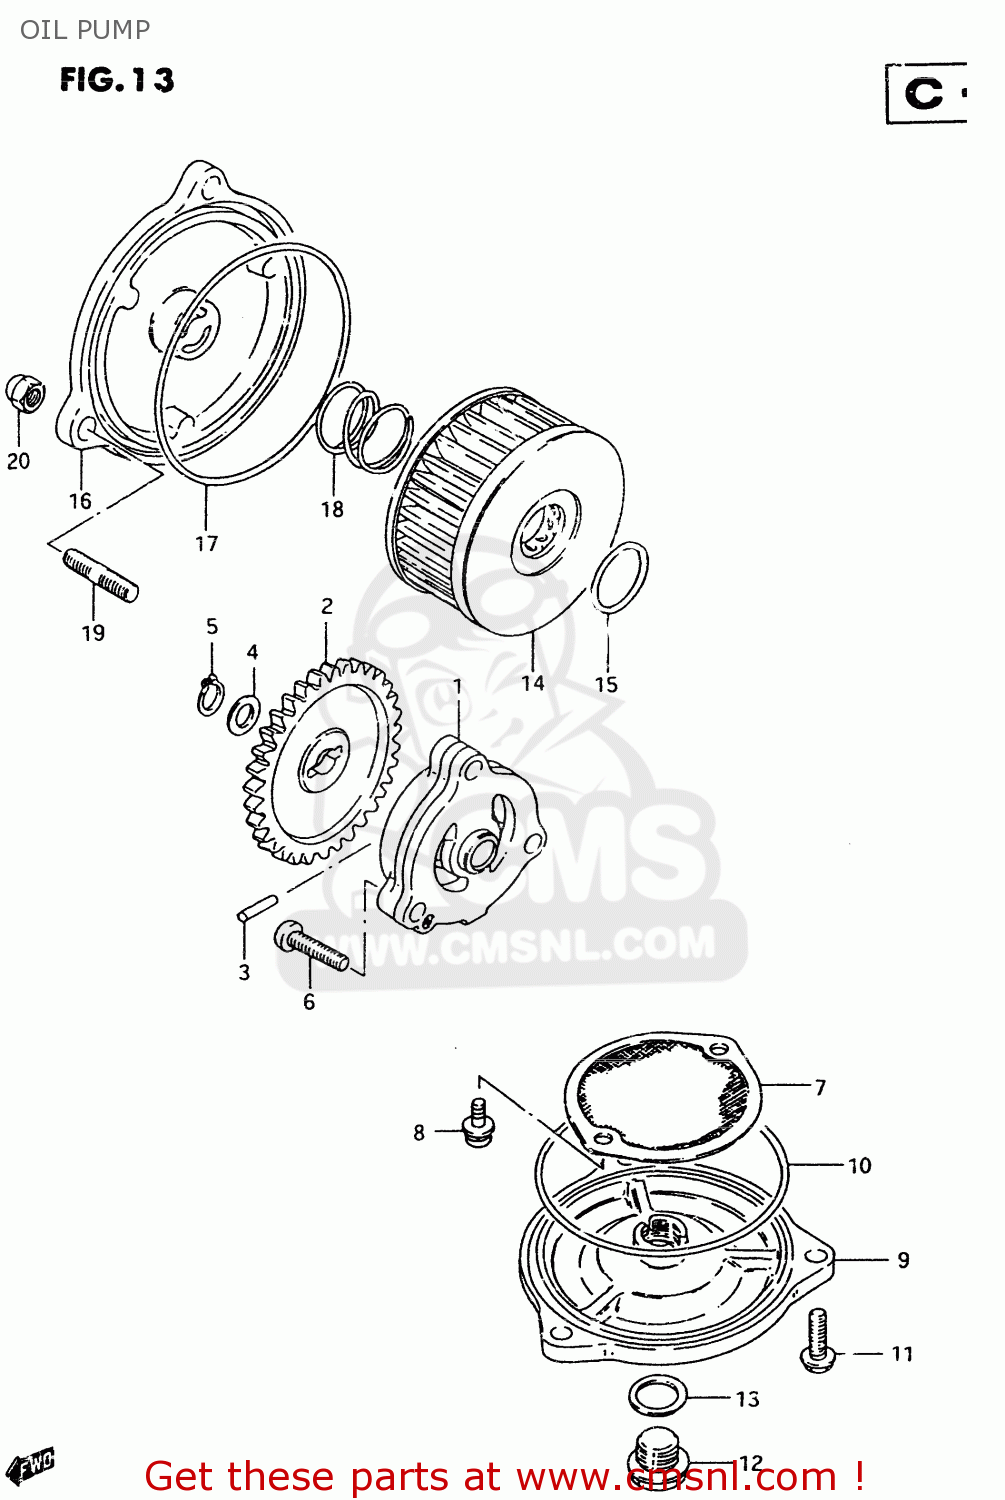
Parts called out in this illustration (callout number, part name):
1	PUMP ASSY,ENGINE OIL
2	GEAR,OIL PUMP DRIVEN(NT:33)
3	PIN(4X15.8)
4	SHIM(10X18X0.5)
5	CIRCLIP,10MM
6	SCREW
7	STRAINER,ENGINE OIL
8	SCREW
9	CAP,OIL STRAINER
10	O RING(D:2.4,ID:85)
11	SCREW
12	PLUG
13	GASKET(13.8X18.8X4.8) (NAS)
14	FILTER ASSY,ENGINE OIL
15	O RING(D:2.4,ID:15.8)
16	CAP,OIL FILTER
17	O RING(D:2.4,ID:73)
18	SPRING
19	STUD 6X12
20	NUT
